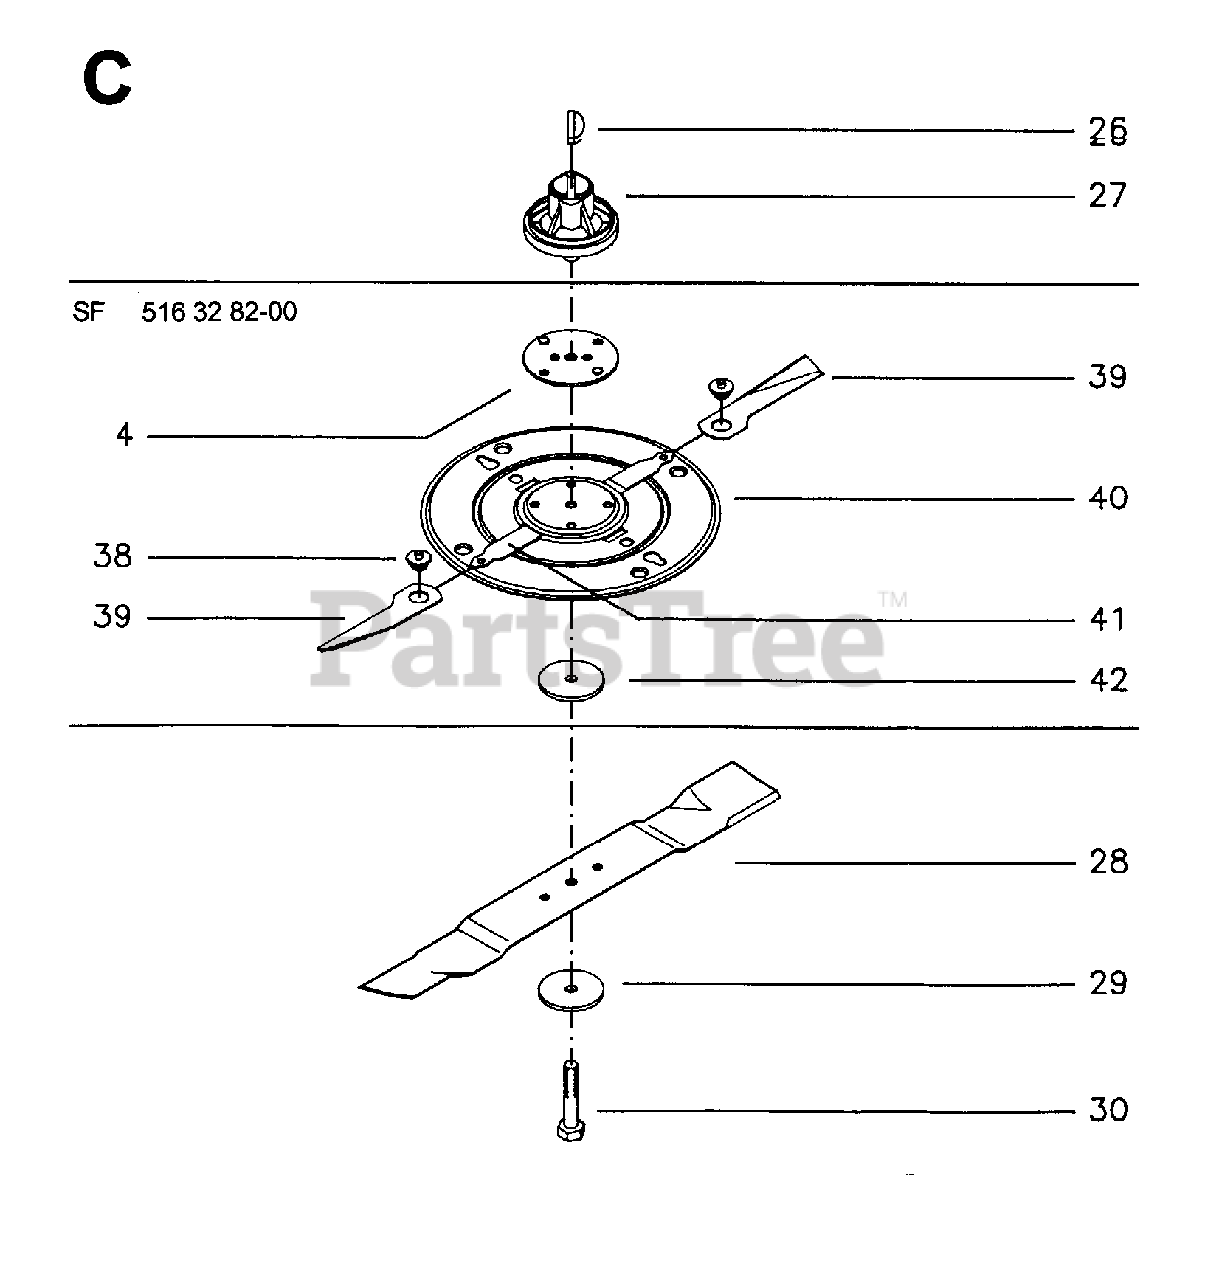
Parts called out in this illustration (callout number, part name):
4	STEEL PLATE ADAPTER
27	BLADE ADAPTER
39	CUTTER BLADE
